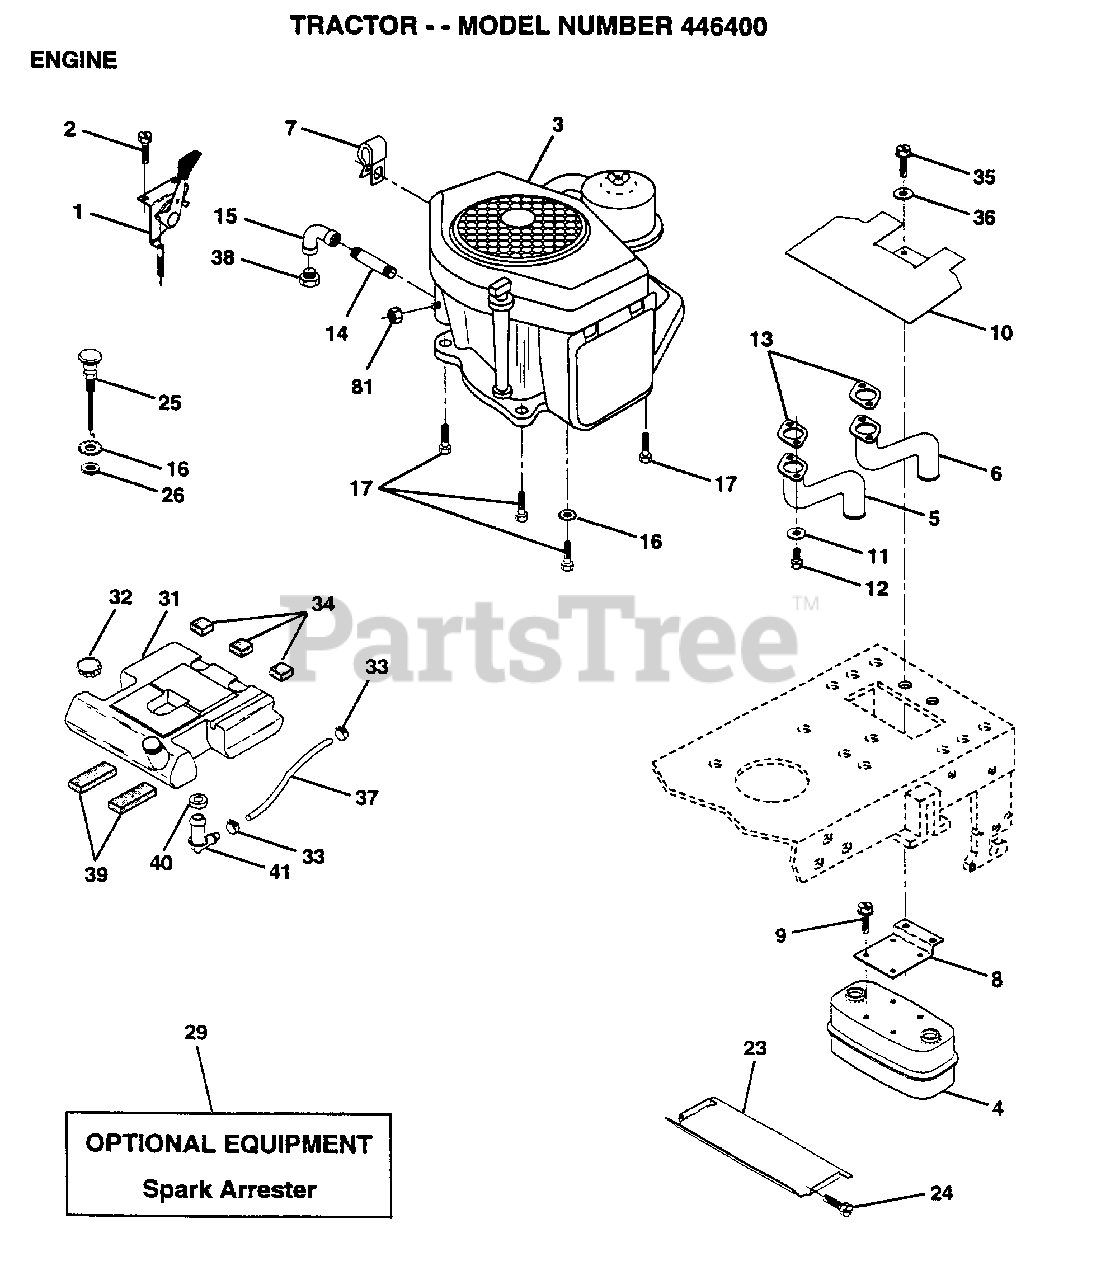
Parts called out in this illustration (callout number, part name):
2	SCREW LT
3	ENGINE, KOHLER
5	PIPE-EXHAUST.LH
6	PIPE-EXHAUST.RH.
7	CLIP T
8	BRACKET MUFFLER
9	SCREW ST
10	SHIELD.HEAT.MUFF.
11	LOCKWASHER
12	SCREW
14	PIPE NIPPLE LT
15	ELBOW
16	LOCKWASHER
17	SCREW LT
18	HEAT SHIELD
19	RECEPTACLE LT
20	RETAINER LT
22	STUD.1/4.TURN
23	HEAT SHIELD
24	SCREW
32	CAP ASM FUEL
33	HOSE CLAMP
34	PAD-SPACER LT
35	SCREW
36	WASHER
37	FUEL LINE T
39	PAD IDLER TI
40	BUSHING OUTLET T
41	STEM.TANK.FUEL
81	NUT
